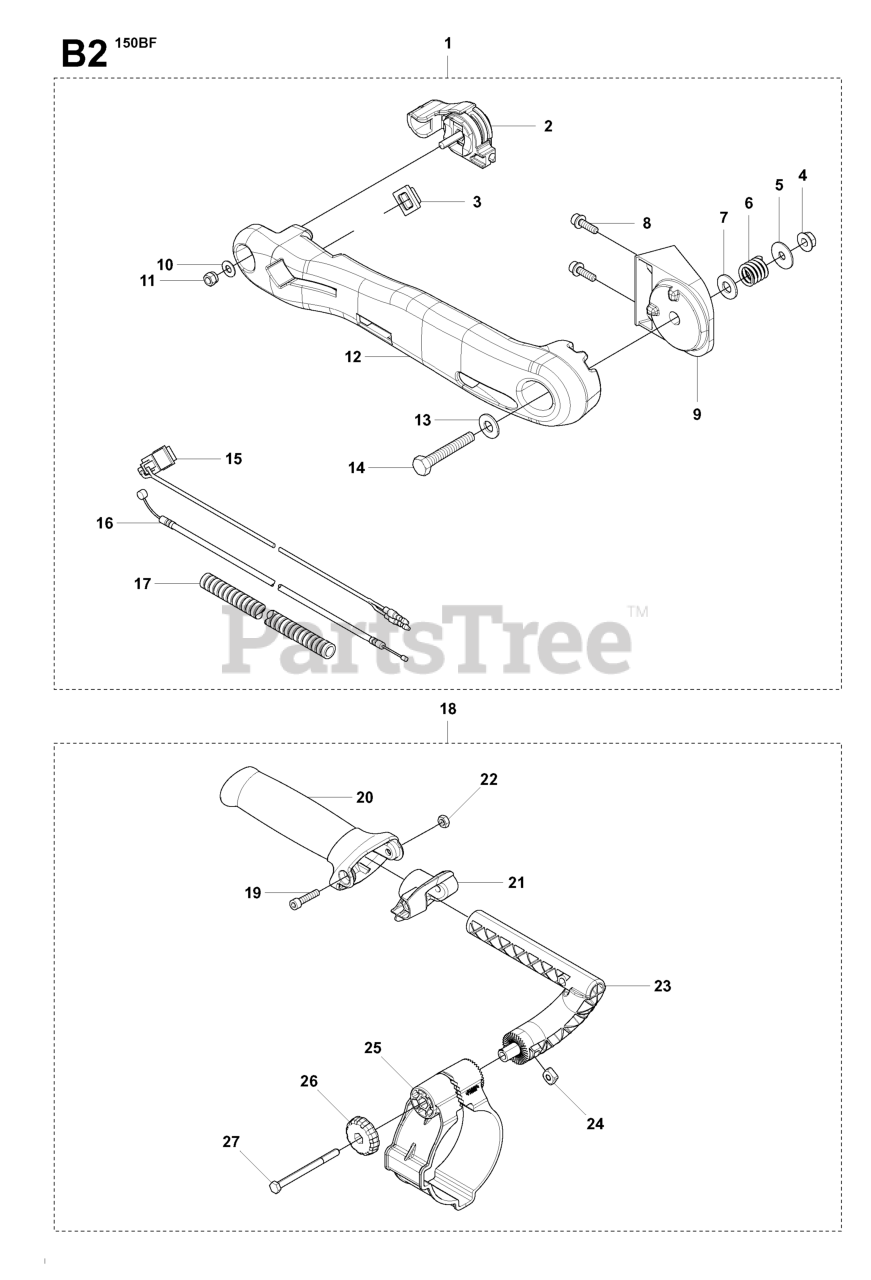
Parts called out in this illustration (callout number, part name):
1	HANDLE ASSY
2	LEVER
3	CAP
4	NUT
5	WASHER
6	SPRING
7	WASHER
8	SCREW
9	RP_BRACKET
11	NUT
12	ARM
13	WASHER
14	BOLT
15	KILL SWITCH
16	CABLE COMP
19	SCREW
23	BRACKET
25	HOLDER TH
